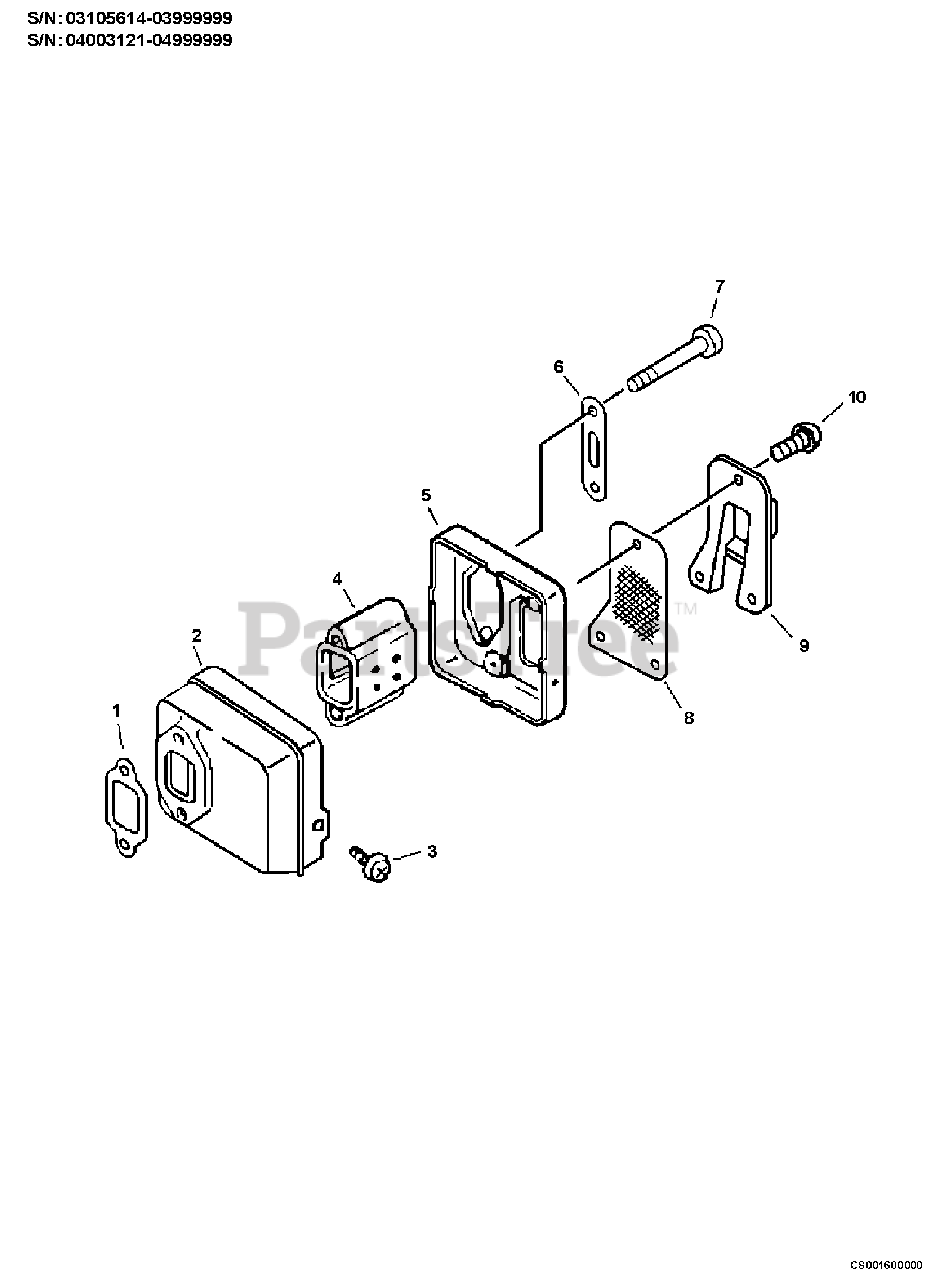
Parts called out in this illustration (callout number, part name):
1	GASKET, MUFFLER
2	MUFFLER
3	SCREW 4
4	PLATE, MUFFLER
5	COVER, MUFFLER
6	PLATE, EYE
7	BOLT 6 MM
8	SCREEN, SPARK ARRESTER
9	COVER, MUFFLER
10	SCREW 4
